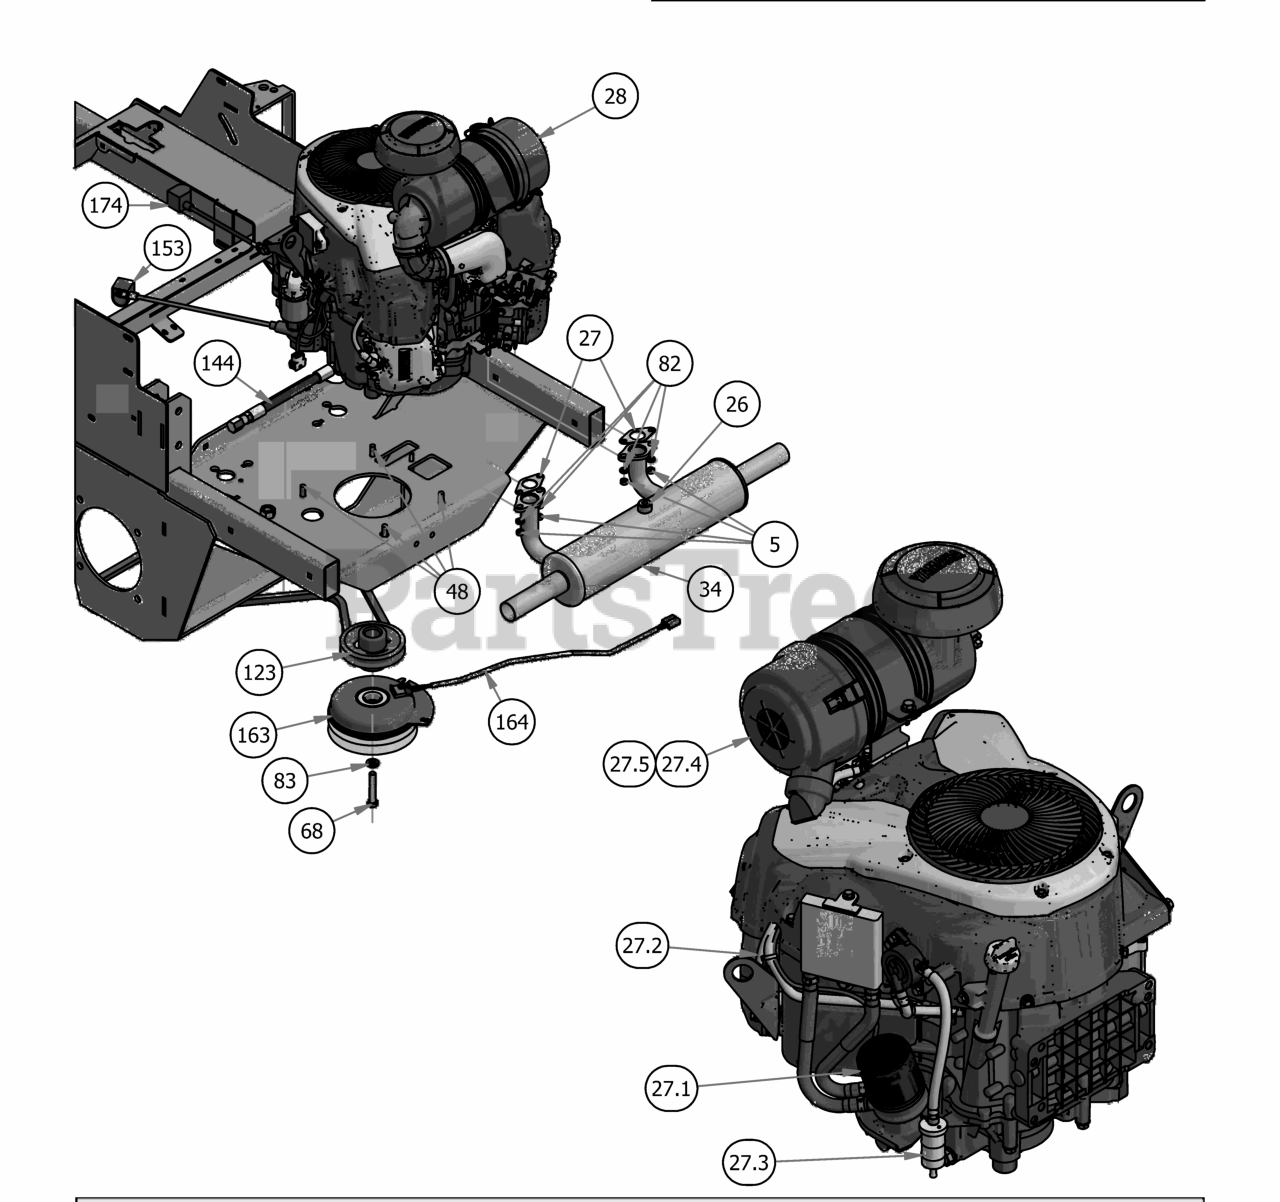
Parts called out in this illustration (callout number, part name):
5	M8-1.25 Zinc Nut
26	O2 Sensor Plug
27	Exhaust Gasket for yamaha
27.1	Oil Filter
27.2	Yamaha Spark Plug
27.3	Yamaha Fuel Filter
27.4	Canister Air Filter- Outer
27.5	Canister Air Filter- Inner
28	Carbureted 27.5hp Yamaha Engine
34	Muffler for 27Hp Yamaha
48	3/8 x 1 1/8 bolt
68	7/16" x 2 1/2" Hex Bolt
82	5/16" Lock Washer
83	7/16" Lock Washer
123	4 3/4 Motor Pulley
132	2019 Rebel Pump Belt
133	1/4 x 2 Square key Stock
144	Oil drain Hose for Yamaha
153	14" Red Battery Cable-Base Outlaw
163	Clutch Assembly
164	Clutch Pigtail
165	2019 Rigid Frame
174	Starter Cable
